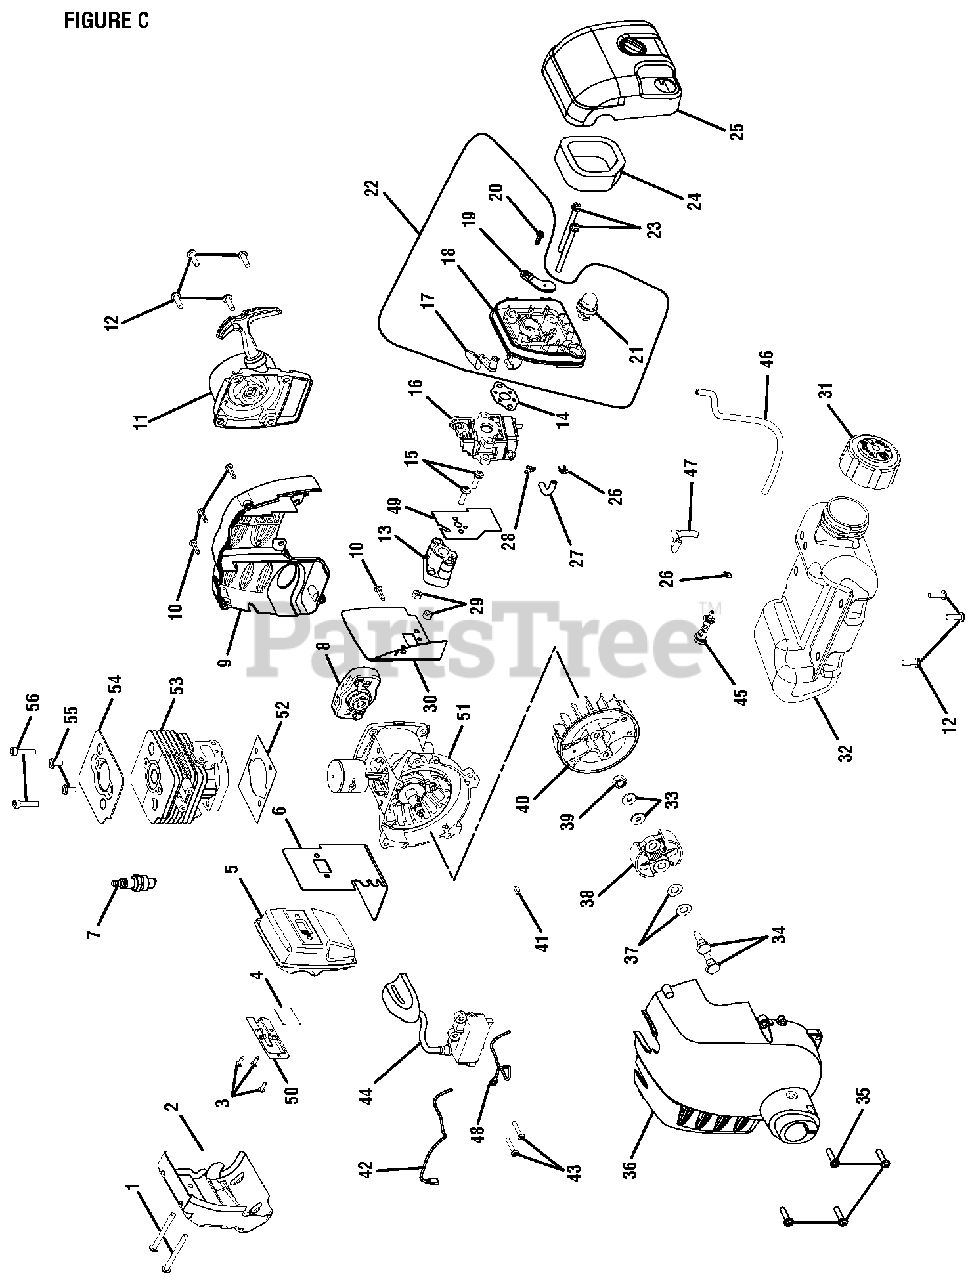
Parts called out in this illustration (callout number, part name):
1	Screw (M5 x 50 mm, Torx Slotted Recessed Pan Hd.)
2	Heat Shield
3	Screw Recess Pan Hd.)
4	Screen
5	Muffler Assembly
6	Muffler Gasket
7	Spark Plug (RCJ4Y)
8	Starter Cup
9	Engine Housing, Rear
10	Screw (M4 x 16 mm, Torx Recessed Pan Hd.)
11	Starter Recoil Assembly
12	Screw (M5 x 16 mm, Torx Slotted)
13	Heat Dam Insulator
14	Carburetor Gasket
15	Screw (M5 x 31 mm Torx Slotted Recessed Pan Hd.)
16	Carburetor Assembly
17	Choke Lever
18	Carburetor Plate
19	Choke Plate
20	Screw (M4 x 12 mm, Slotted Recessed Pan Hd.)
21	Primer Assembly
22	Filter Housing Assembly
23	Screw (M5 x 60 mm, Slotted Recessed Pan Hd. Machine)
24	Element
25	Cover Assembly
26	Hose Clip
27	Fuel Line (45 mm)
28	Hose Clip
29	Nut (M5 x .8 mm)
30	Insulator Gasket
31	Fuel Cap Assembly
32	Fuel Tank and Cap Assembly
33	Washer
34	Clutch Screw
35	Screw (M5 x 20 mm Torx Slotted Recessed Pan Hd.)
36	Front Housing Assembly
37	Curved Washer
38	Clutch Assembly
39	Rotor Nut
41	Woodruff Key 10 mm x 3 mm)
42	Lead Wire, Black
43	Screw (M4 x 22 mm, Torx Slotted Recessed Pan Hd.)
44	Coil Boot Assembly
45	Fuel Filter
46	Fuel Line (150 mm) [LP1500]
47	Fuel Line (118 mm)
48	Lead Wire, Red
50	Trimmer Outlet
51	Crankcase Assembly
53	Cylinder
54	Cylinder Plate
55	Screw (M5 x 10 in., Torx Recessed Pan Hd.)
56	Screw (M5 x 22 mm, Soc. Hd.)
